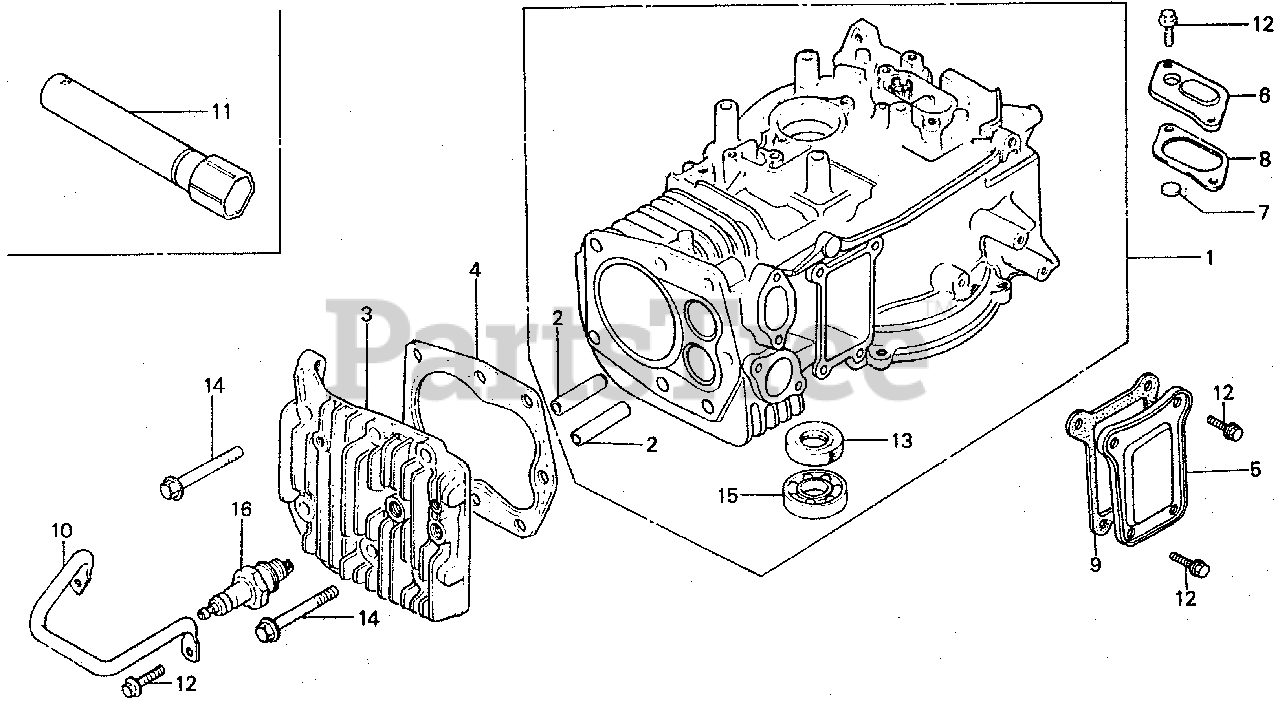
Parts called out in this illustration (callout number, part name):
1	CYLINDER ASSY.
2	GUIDE, VALVE (OS)
3	CYLINDER HEAD
4	GASKET, CYLINDER HEAD
5	COVER, TAPPET
6	CAP, BREATHER CHAMBER
7	VALVE, BREATHER
8	GASKET, BREATHER CAP
9	GASKET, TAPPET COVER
10	GUARD, PLUG
11	WRENCH, SPARK PLUG
12	BOLT, FLANGE (6X12) (CT200)
13	OIL SEAL (25X41X6)
14	BOLT, FLANGE (8X45)
15	BEARING, RADIAL BALL (6205)
16	SPARK PLUG (BM6A) (NGK)
16	SPARK PLUG (W20M-U) (DENSO)
